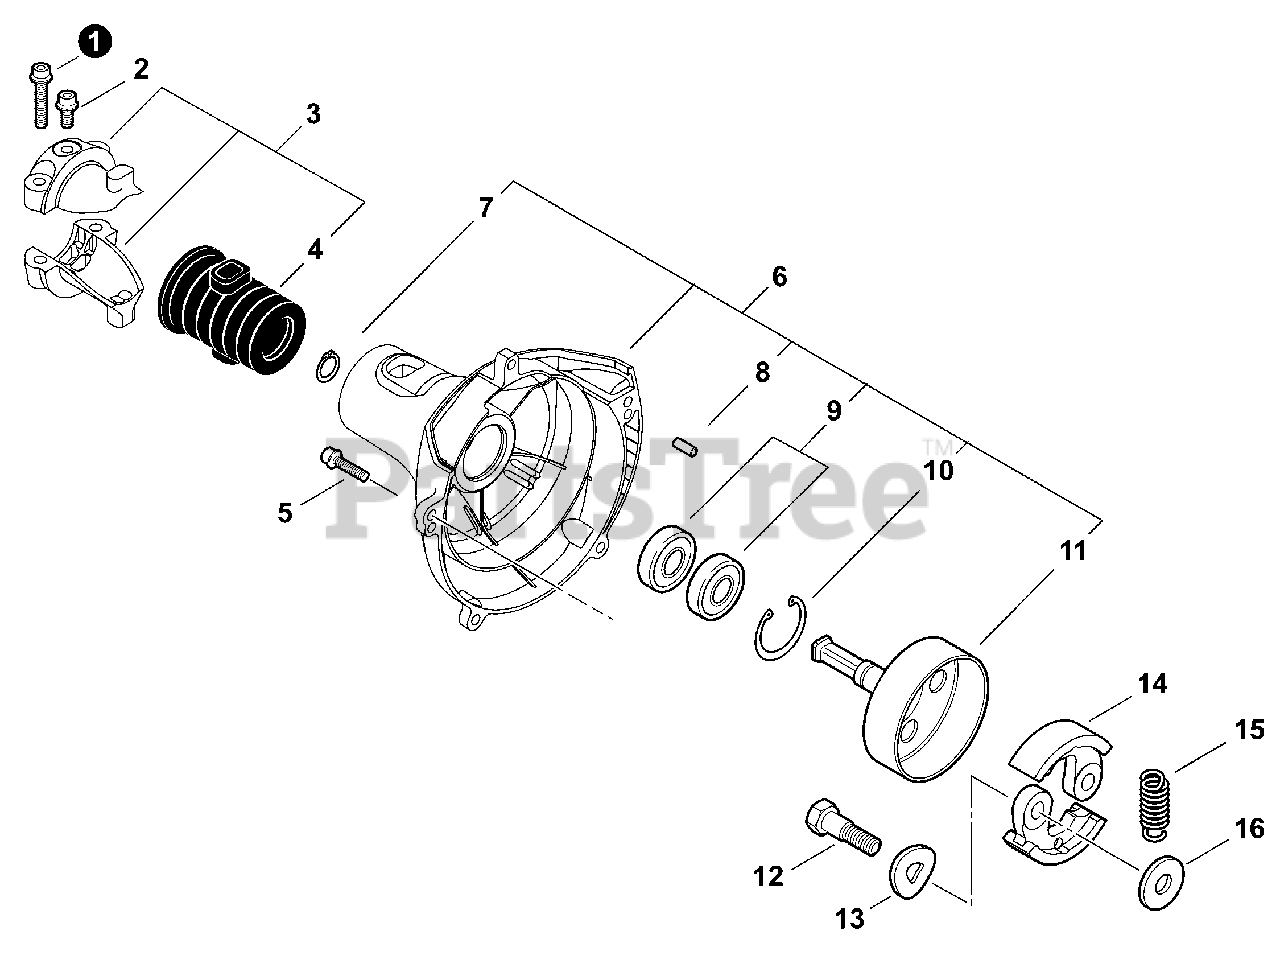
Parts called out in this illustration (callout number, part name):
1	SCREW - 5×25
2	SCREW - 5×10
3	MAIN PIPE FIXTURE KIT
4	CUSHION
5	SCREW - 5×20
6	FAN CASE ASY
7	RING, RETAINING - 12
8	PIN, DOWEL
9	BEARING, BALL - 6001
10	RING, RETAINING - 28
11	DRUM, CLUTCH
12	BOLT, CLUTCH
13	WASHER - SPRING
14	SHOE, CLUTCH
15	SPRING, CLUTCH
16	WASHER - 6
